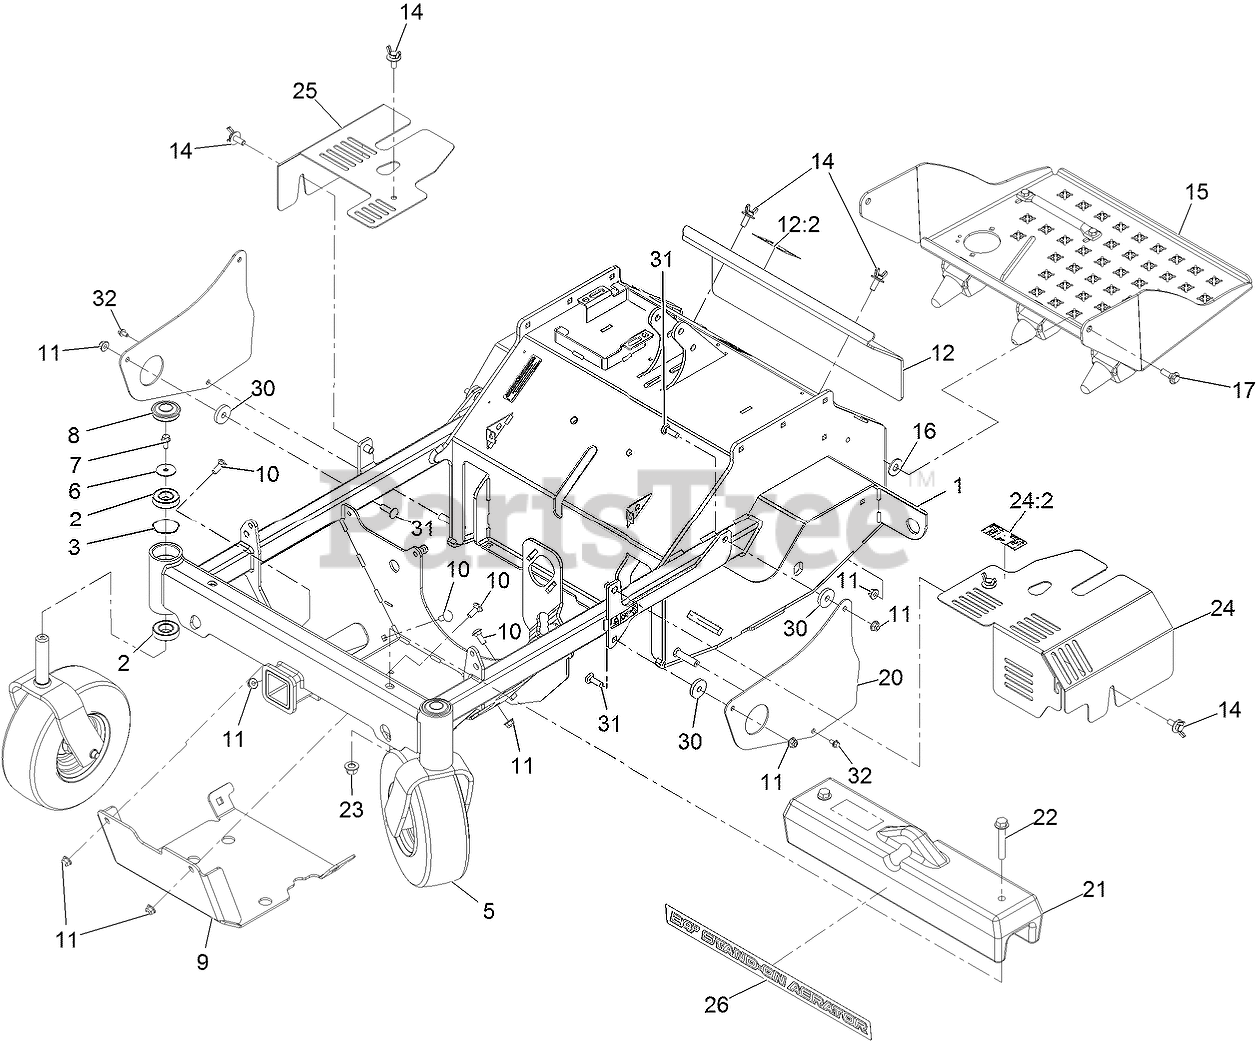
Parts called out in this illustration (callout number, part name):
1	Main Frame ASM
2	BEARING-BALL
5	Front Caster ASM
6	WASHER-FLAT
7	SCREW-HHF
8	CAP-GREASE
9	GUARD-ENGINE
10	BOLT-CARR
11	NUT-HF, NI
12	ACCESS COVER ASM
12:2	DECAL-OPERATION, TINE GRO
14	Screw-Sems (3/8-16 X 1)
15	PLATFORM ASM
16	WASHER-FLAT
17	SCREW-SHOULDER, HWH
20	Guard-Chain
21	WEIGHT-FRONT
22	SCREW-HF
23	Nut-Lock 1/2-13
24	HYDRO-COVER
24:2	DECAL-RELEASE, DRIVE
25	COVER-HYDRO
26	DECAL-STANDON AERATOR 24
30	WASHER-CLUTCH
31	BOLT-CARR
32	SCREW-HHF
